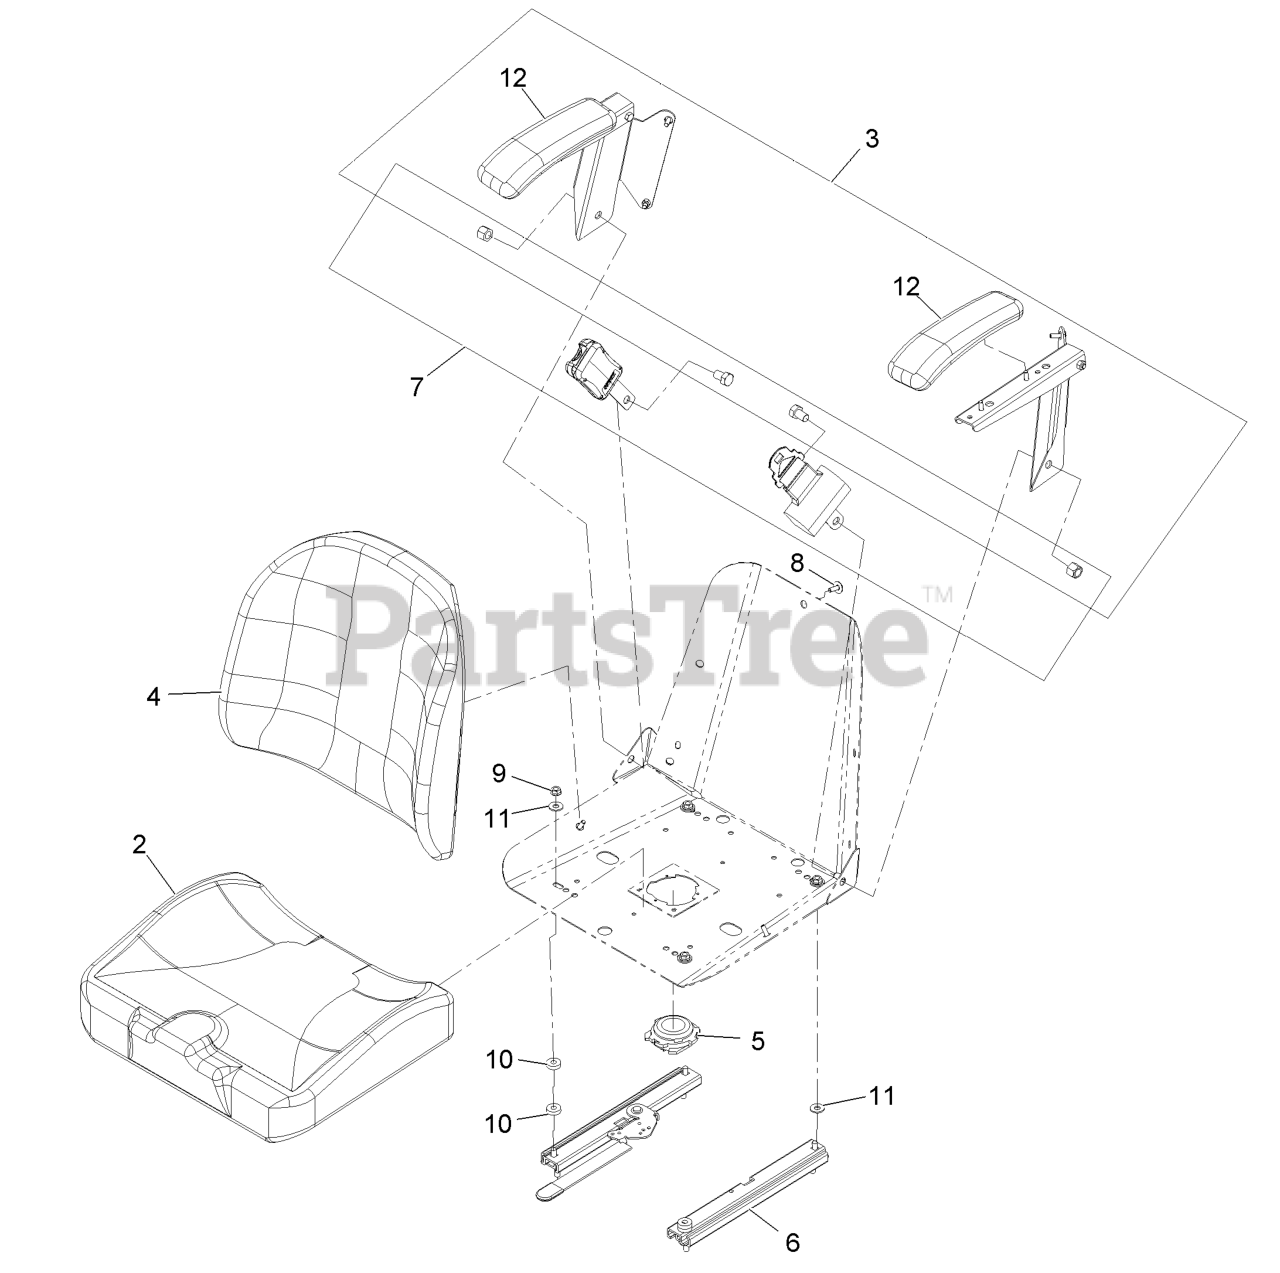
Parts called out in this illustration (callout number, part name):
2	CUSHION,SEAT BOTTOM
3	ARMREST KIT
4	CUSHION,SEAT BACK
5	SWITCH-SEAT
6	TRACK-SEAT
7	SEAT BELT KIT
8	BOLT-SEAT
11	WASHER-FLAT
12	CUSHION-REST, ARM
